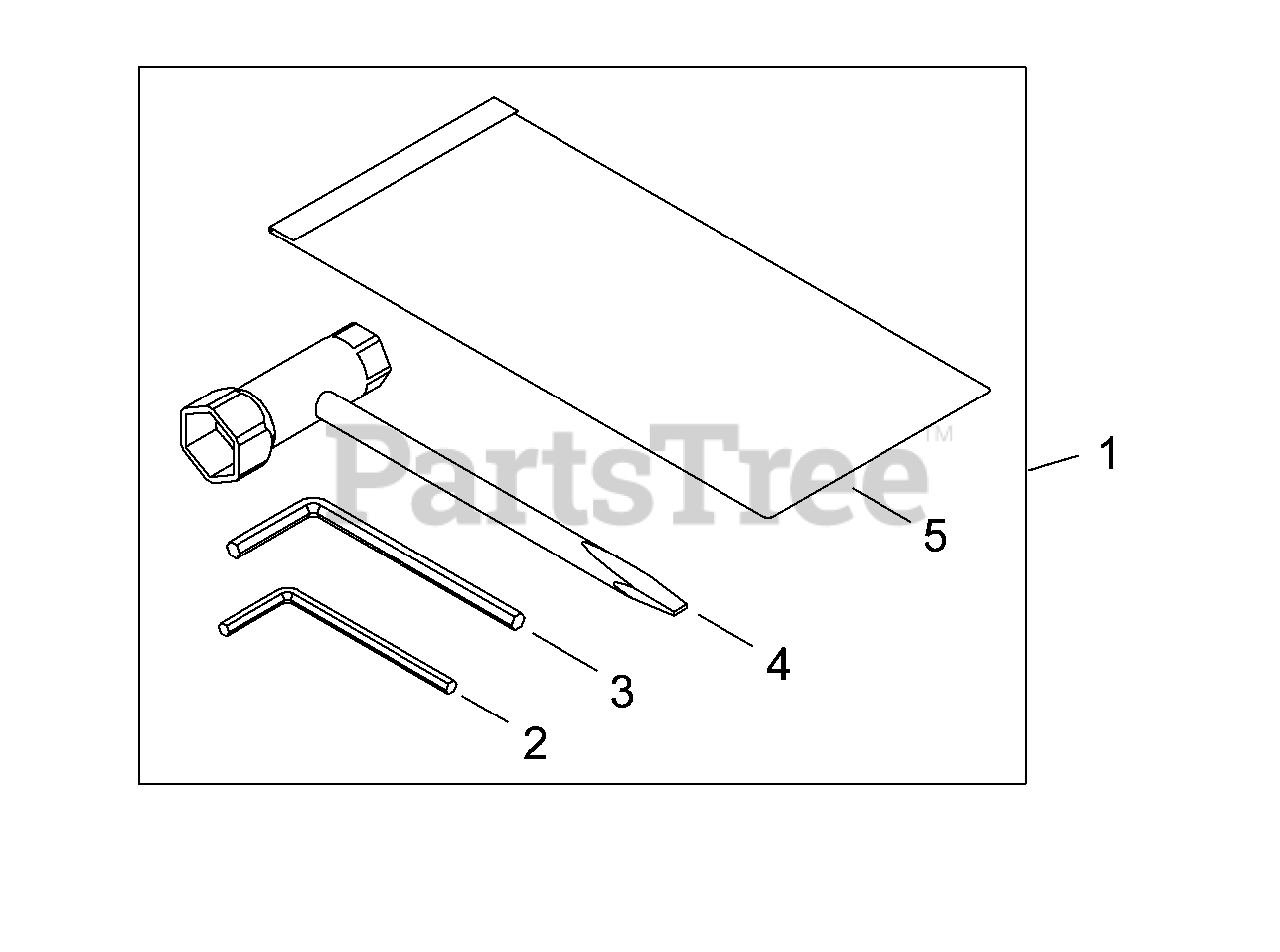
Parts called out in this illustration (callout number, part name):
1	TOOL KIT, SERVICE
2	WRENCH, ALLEN 4 MM
3	WRENCH, ALLEN 5 MM
4	T-WRENCH 13×19 MM
5	BAG, TOOL
